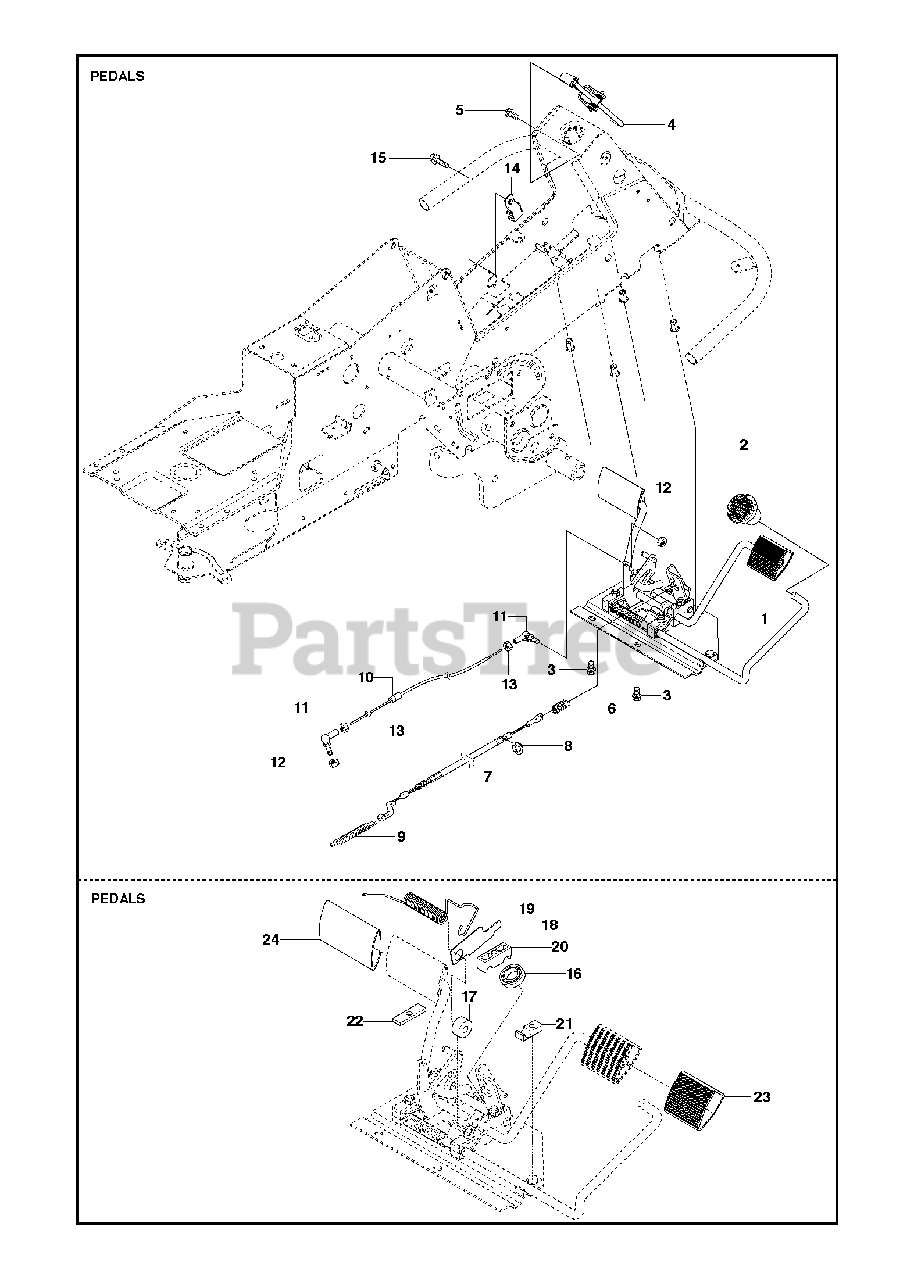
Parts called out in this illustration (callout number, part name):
1	PEDAL ASSEMBLY
2	KNOB
4	BRAKE LEVER ASSY
7	BRAKE WIRE
10	CONTROL CABLE
11	CONNECTOR
12	LOCKNUT M5
16	BALL BEARING 6002-2RS1
17	ROLLER
18	PLATE
19	SPRING
20	PEDAL SHAFT CLAMP
21	SUPPORT
22	PLATE
23	PEDAL RUBBER
24	PEDAL RUBBER, SF
